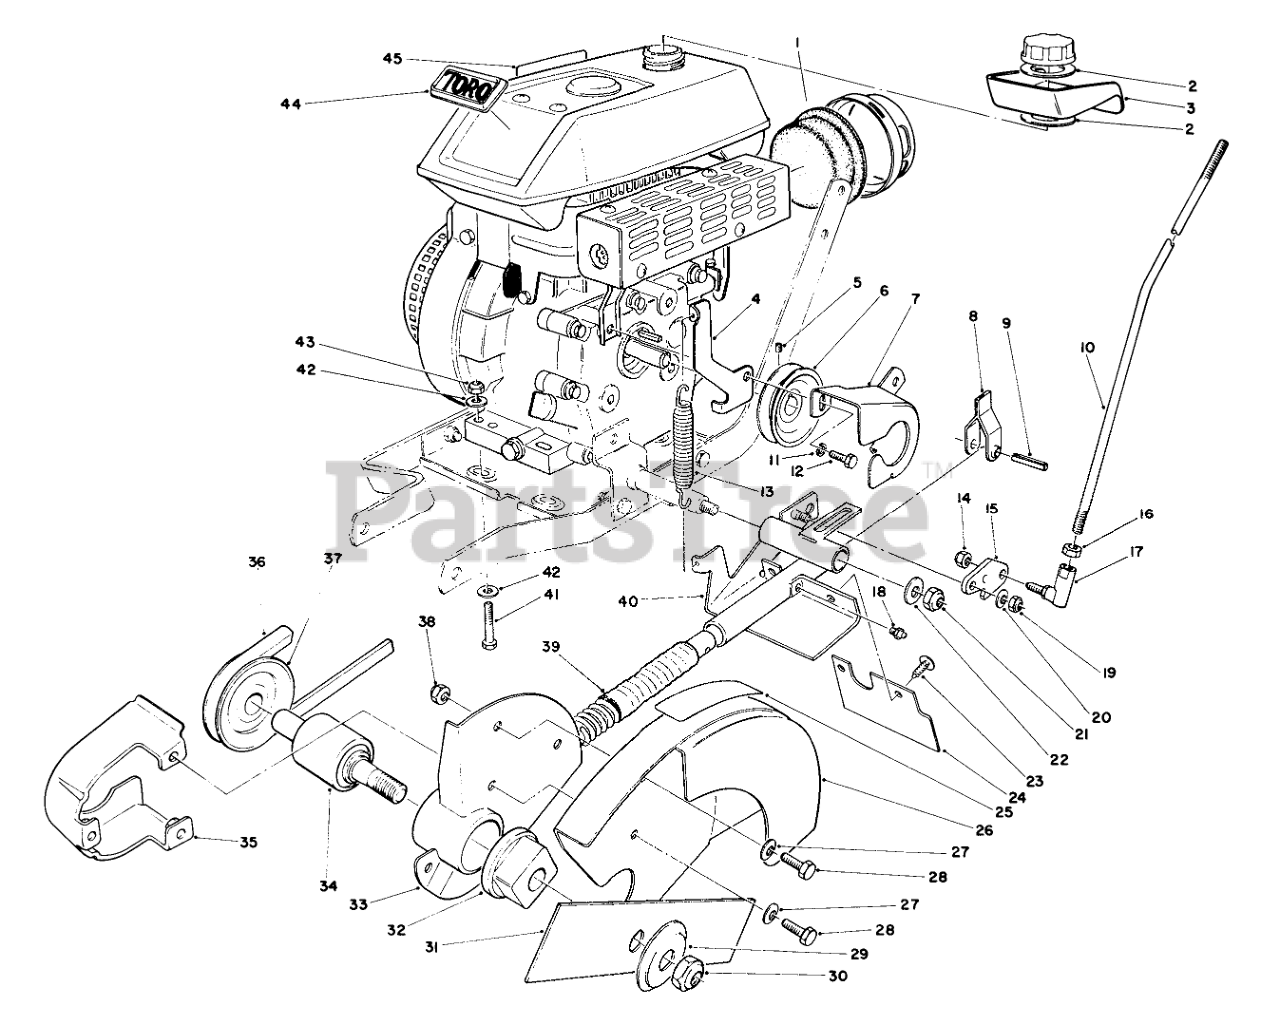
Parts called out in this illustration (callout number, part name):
1	FILTER FOAM
2	WASHER,FUEL DEFLECTOR
3	Deflector-Fuel
4	SPRING BRKT R
5	SCREW-SET
6	2HP PULLEY
7	ENG. PULLEY GUARD
8	LEVER WA R
9	SPIROL PIN 1/4" X 1.25"
10	Rod-Lower
11	WASHER-LOCK
12	BOLT
13	EXT. SPRING
14	NUT-LOCK
15	LEVER LOCK WA
16	NUT-HJ
17	BALL JOINT
18	FITTING-GREASE
19	NUT-LOCK, NI
20	WASHER-FLAT
21	NUT-LOCK, NI
22	WASHER-PLAIN
23	PANEL FASTENER
24	RUBBER GUARD
25	BLADE WARNING DECAL
26	Blade Guard Assembly
27	WASHER-BELLEVILLE
28	SCREW-HWHTF
29	WASHER-BELLEVILLE
30	NUT-HEX
31	Blade-9"
32	BRG SHIELD
33	HUB SHAFT WA RO
34	Spindle Assembly
35	PULLEY GUARD WA
36	V-BELT
37	PULLEY-SPINDLE ASM
38	NUT-HEX
39	SPRING & BELLOW ASM
40	Pivot Arm Bracket Assembly
41	SCREW-HH
42	WASHER-PLAIN
43	NUT-LOCK, NI
44	TORO LOGO PLT
45	OPERATING INST DECAL
